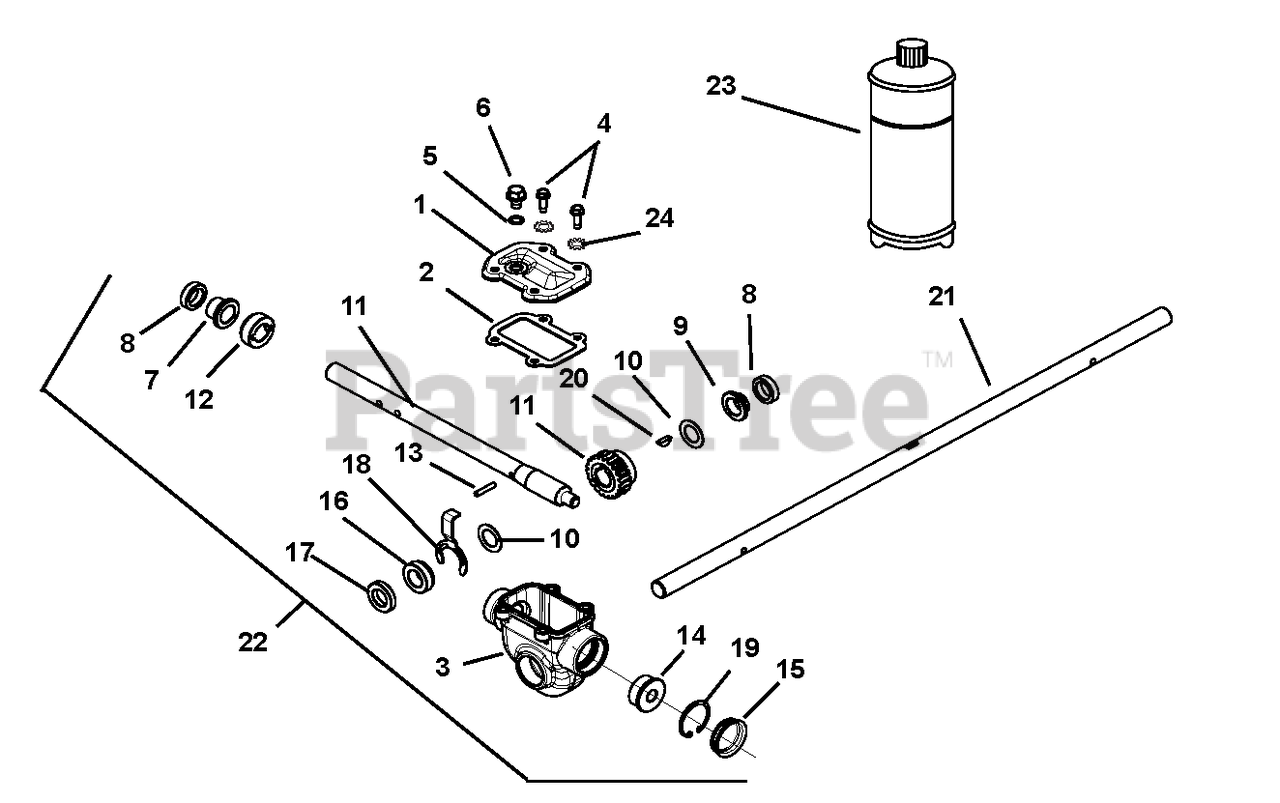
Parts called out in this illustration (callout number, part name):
1	COVER, TOP - COMPACT
2	GASKET, TOP - COMPACT GEARCASE
3	GEARCASE, COMPACT MACHINED
4	@BLT-HEX .25-20X.50 GR5 YWZC
5	WSHR-BND-SEAL .38X.75X.11 GALV
6	@SCR-ROLOK .38-16X.50 HWH YWZC
7	BSHG-FLG .755X.878X.75X1.25
8	SEAL-OIL .748X1.125X.312 TB2-H
9	BSHG-FLG .755X.878X.424X1.25
10	WSHR-FL-STL .760X1.225X.032 YZ
11	SHAFT AND WORM GEAR ASSEMBLY
12	THRUST COLLAR, .75" ID SLIPFIT
13	PIN-STR .188X1.00 6150
14	BSHG-FLG .503X1.303X.62X1.465
15	COVER, GEAR CASE 1.50"
16	BSHG-FLG COMPACT, RIGHT
17	SEAL-OIL .748X1.300X.250 TB2-H
18	BUSHING RETAINER, COMPACT
19	RG-RTNG-INT 1.500X.050
20	KEY-WDRF .19X.63 HRD #61
21	SHAFT, RAKE - 24" (.750 DIA)
22	GEAR CASE, 24" IRON SM TOP-LD
23	ARIENS L3 LUBE, 8 OZ BOTTLE
24	@WSHR-LK-EXT.262X.502X.026YWZC
